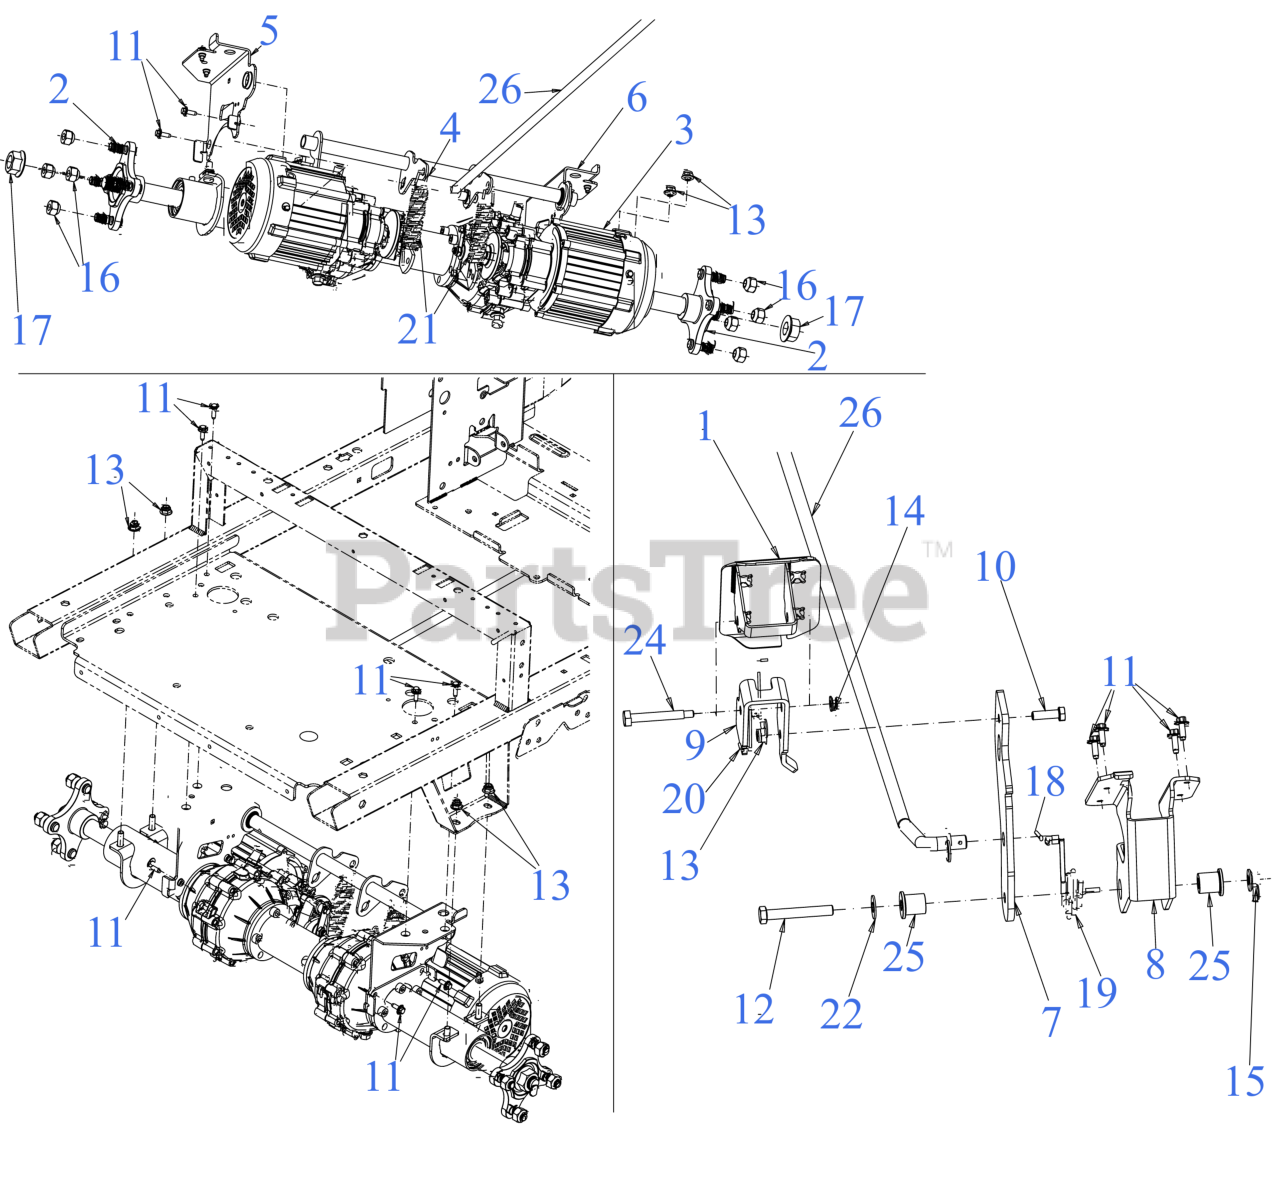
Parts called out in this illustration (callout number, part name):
1	PARK BRAKE PEDAL
2	WHEEL HUB ASSEMBLY
2	STUD 7/16-14 x 1.6
3	TRANSMISSION (ELECTRIC)
4	ELECTRIC BRAKE SHAFT
5	TRANSMISSION SUPPORT (RH)
6	TRANSMISSION SUPPORT (LH)
7	BRAKE PEDAL
8	BRAKE PEDAL SUPPORT
9	BRAKE PEDAL MOUNT
10	SCREW 5/16-18 x 1.0 GR5
11	SCREW M6-1 x .625
12	HEX SCREW-3/8-16X2.5 GR5
13	FLANGE LOCK NUT 5/16-18
14	FLANGE LOCK NUT
16	LUG NUT 7/16-14
17	HEX FLANGE NUT 3/4
18	COTTER PIN
19	TORSION SPRING 1.391 ID x .56 LG
20	TORSION SPRING .405 ID x .425 LG
21	SPRING .925 DIA x 5.37
22	FLAT WASHER
24	SHOULDER SCREW
25	FLANGE BEARING (.38x.75x.77)
26	BRAKE ROD
